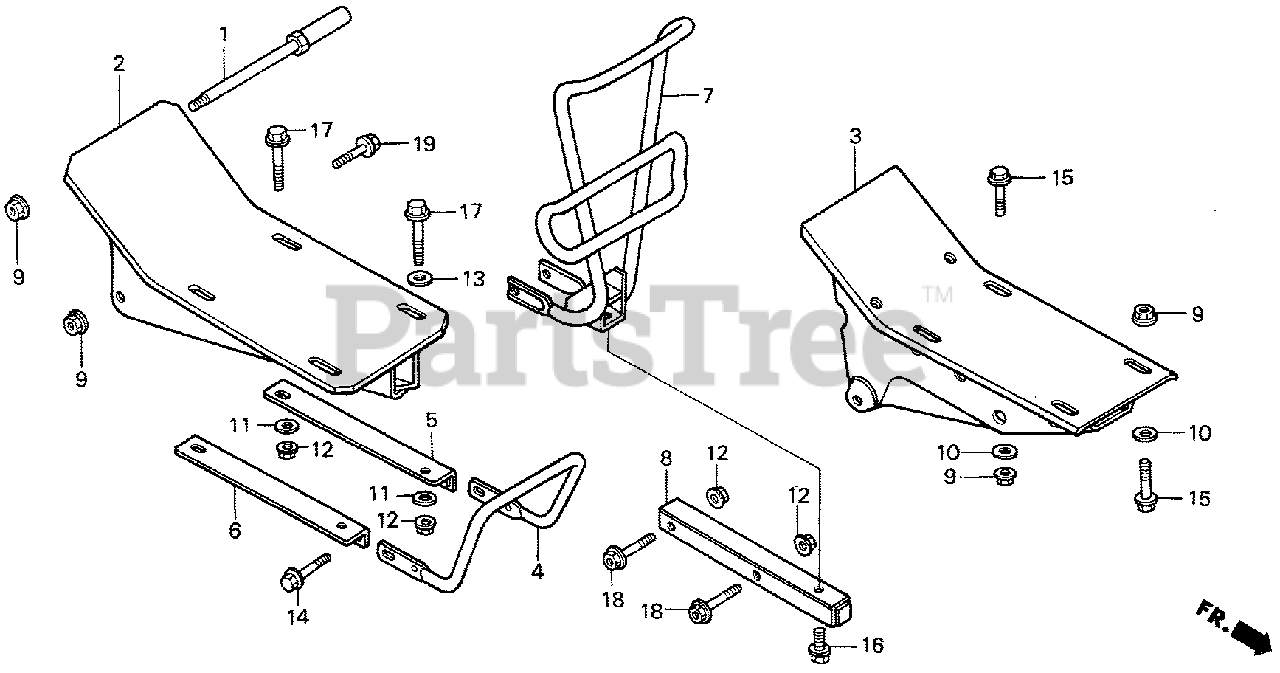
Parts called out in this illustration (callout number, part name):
1	BOLT, TENSIONER ARM
2	BED, ENGINE
4	PIPE, FR. GUARD
5	STAY A, GUARD PIPE
6	STAY B, GUARD PIPE
7	GUARD, FR.
8	BEAM, WEIGHT
9	NUT, FLANGE (8MM)
11	WASHER, EX. MANIFOLD
12	NUT, FLANGE (10MM)
13	WASHER, PLAIN (10MM)
14	BOLT, FLANGE (8X14)
16	BOLT, FLANGE (10X25)
17	BOLT, FLANGE (10X50)
18	BOLT, FLANGE (10X50)
19	BOLT, FLANGE (8X45)
